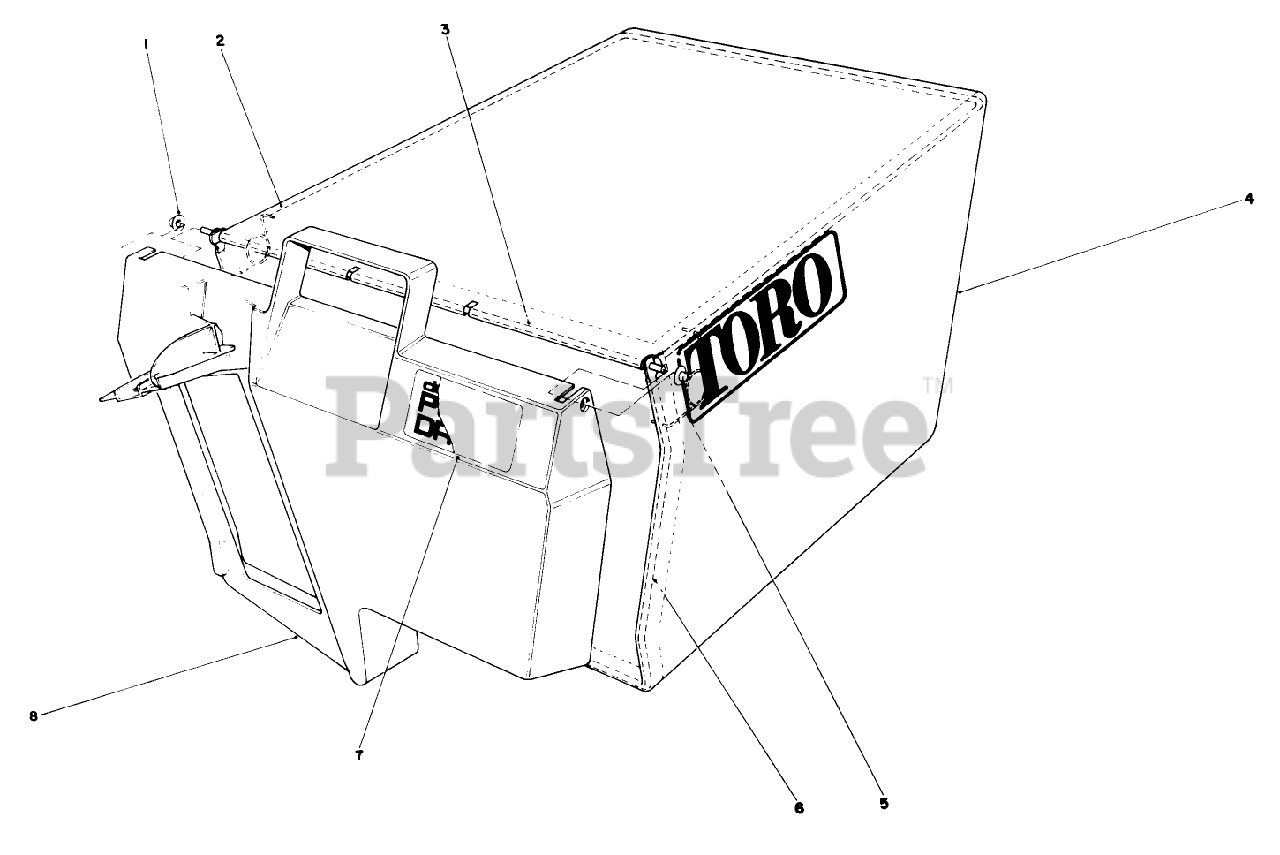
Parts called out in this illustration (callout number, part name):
1	NUT-PUSH
3	HINGE-DOOR, BAG
4	BAG-GRASS
5	SPRING
6	FRAME-BAG
7	BAG DOOR DECAL
8	DOOR-BAG
